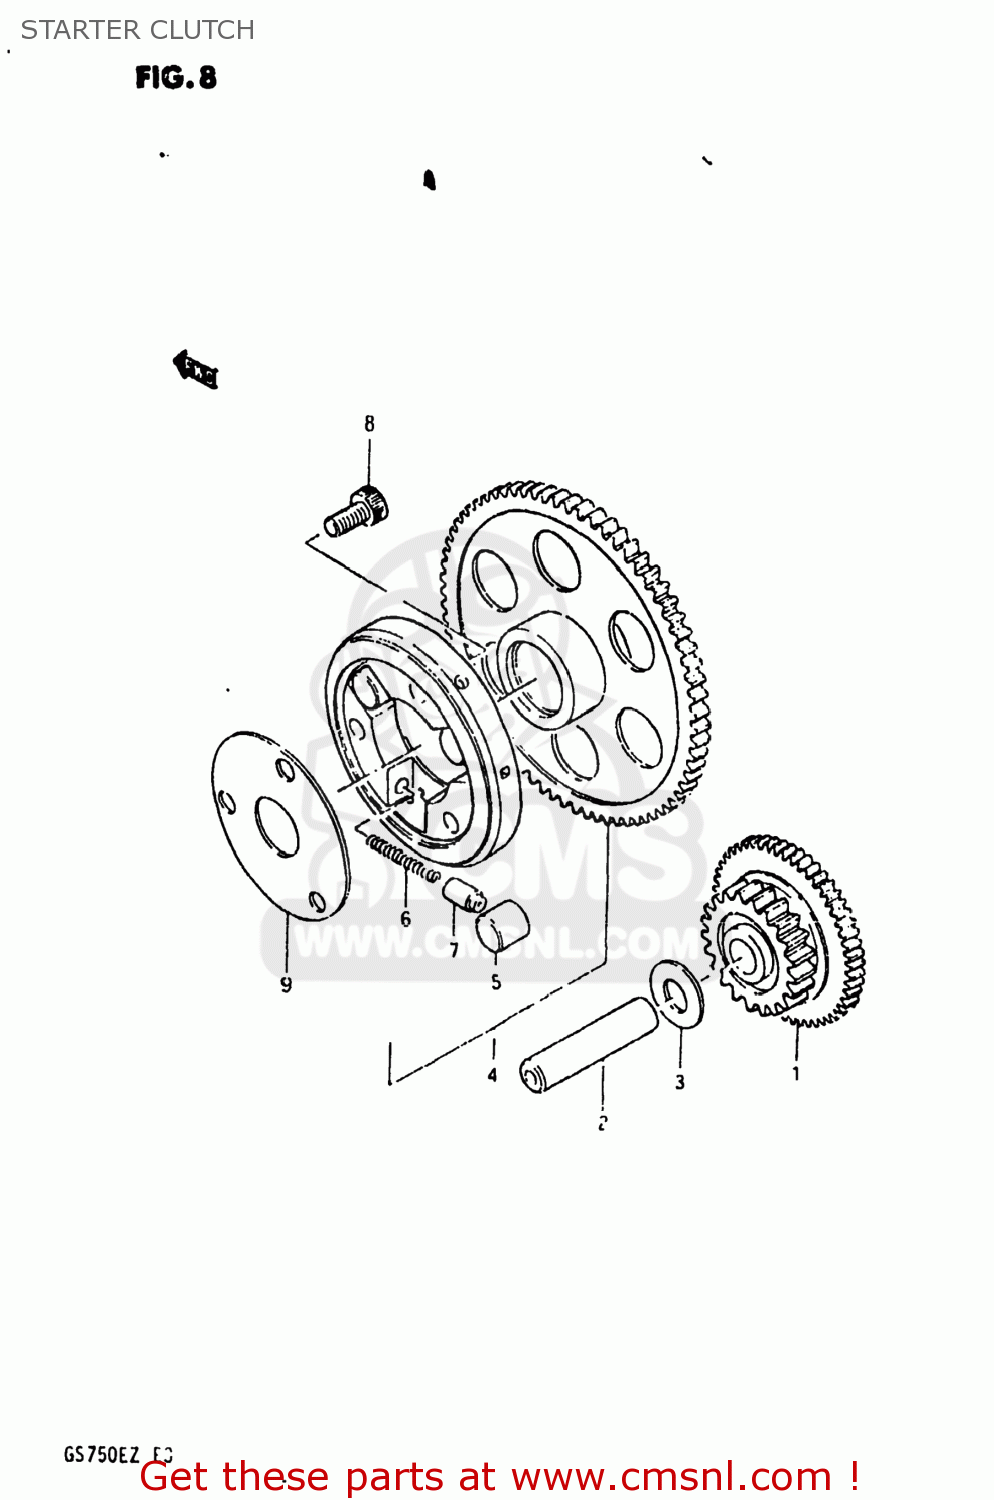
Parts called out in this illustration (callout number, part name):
1	GEAR,STARTER IDLE
2	PIN(7.4X13X56)
3	WASHER
4	CLUTCH SET,STARTER
5	ROLLER(15X13)
6	SPRING
7	PIECE,PUSH
8	BOLT
9	SHIM,STARTER CLUTCH HUB
